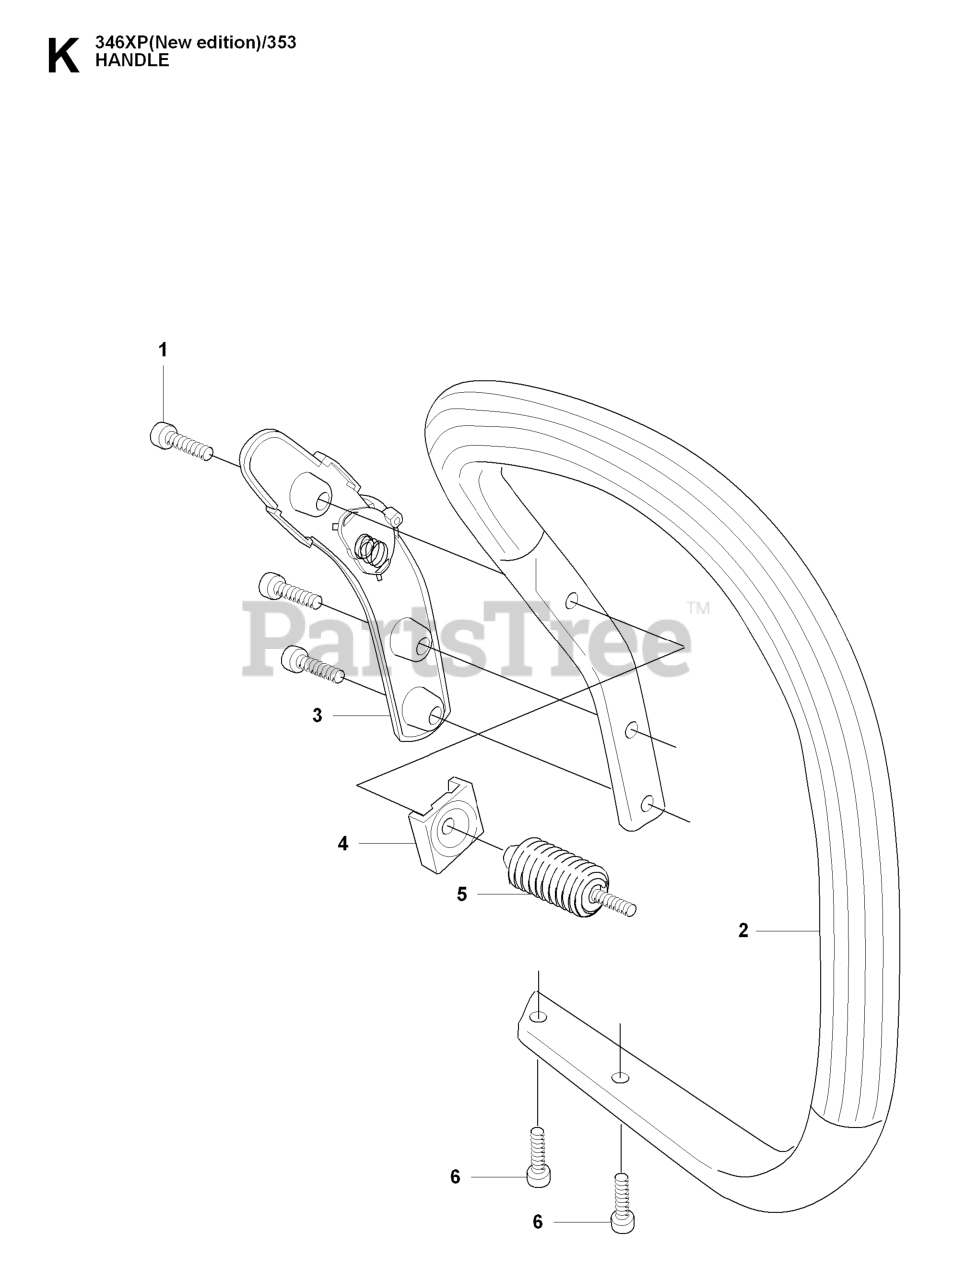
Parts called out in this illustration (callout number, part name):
2	FRONT HANDLE
3	SWITCH
6	SCREW IHSCFT
